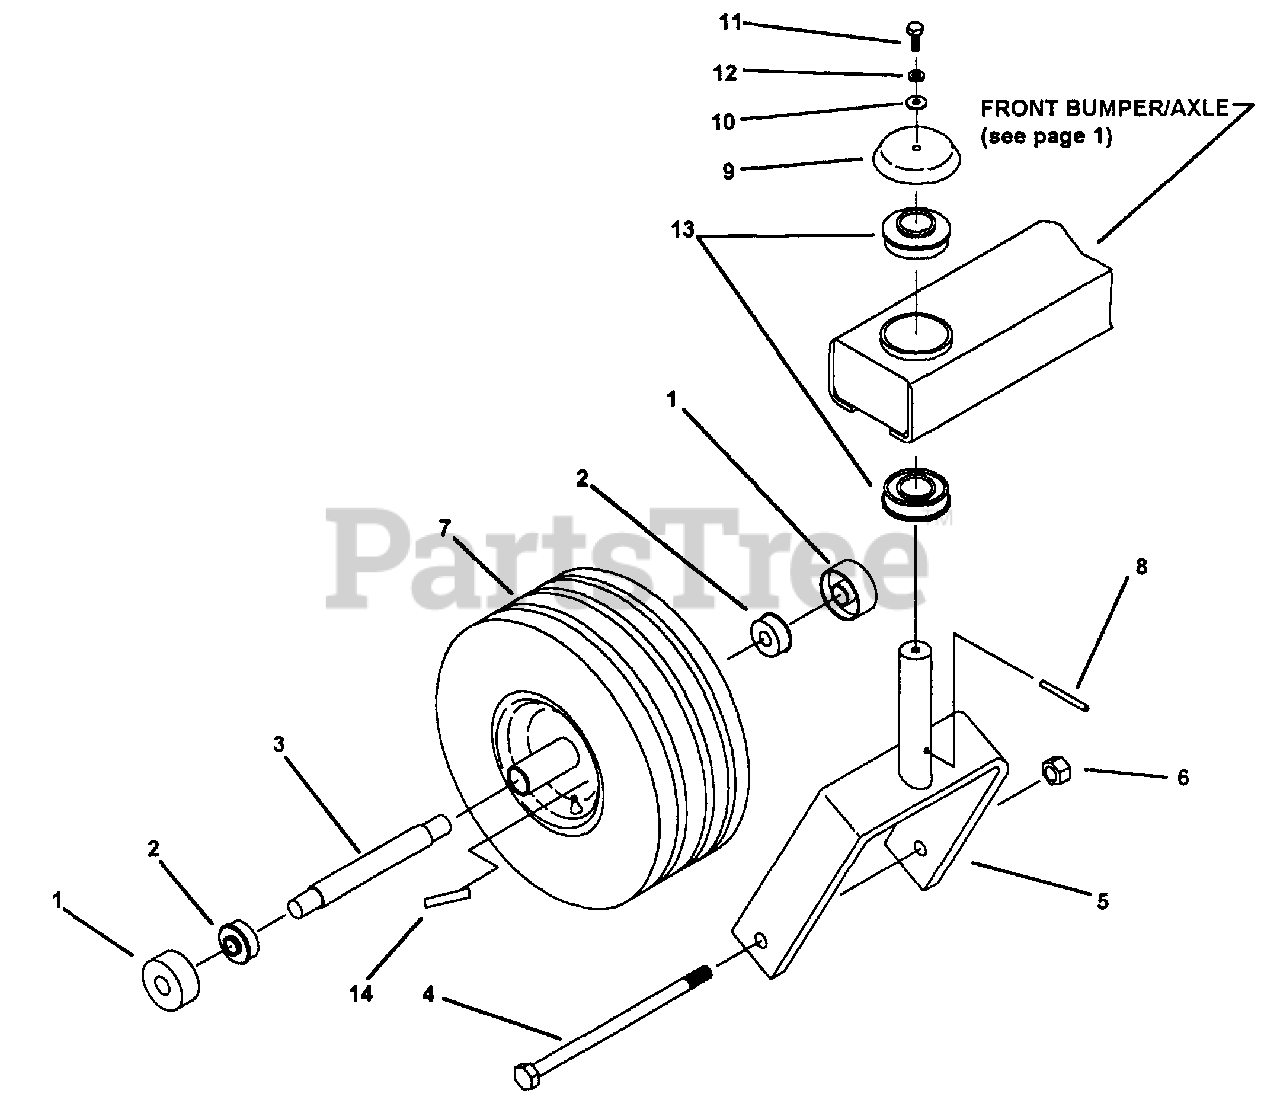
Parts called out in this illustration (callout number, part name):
1	SHIELD, BEARING
2	BEARING, 5/8 I.D. X 1-3/8 O.D.
3	SPACER, BEARING
4	BOLT, 1/2-13 X 8" GR.5
5	CASTER WELDMENT
6	NUT, 1/2-13, STOVER
7	TIRE, 13X5-6, ON WHEEL, (STUDDED TREAD)
7	TIRE, 13X5-6, ON WHEEL, (RIBBED TREAD)
8	PIN, SPIRAL, 3/16 X 2 HEAVY DUTY
9	CAP, BEARING
10	WASHER, FLAT STD. 1/4"
11	BOLT, 1/4-20 X 3/4" GR.5 W/NYLON PATCH
12	LOCKWASHER, 1/4" HEAVY SPRING
13	BEARING, SPD SF-16-32 W/0 COLLAR
14	DECAL, "TIRE PRESSURE..."
